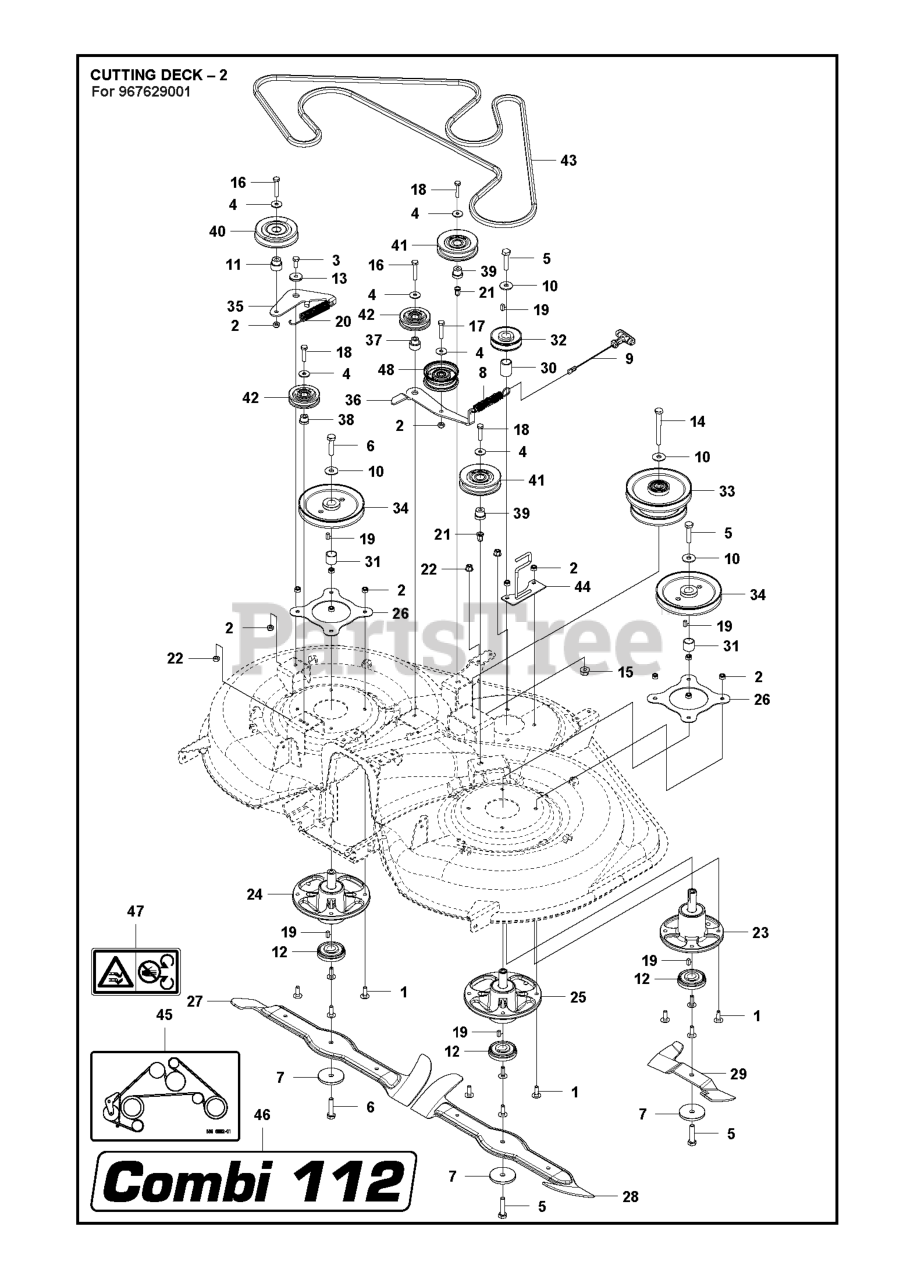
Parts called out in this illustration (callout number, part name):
2	LOCKNUT M8
13	WASHER
16	SCREW
22	NUT FLANGE
48	IDLER PULLEY
